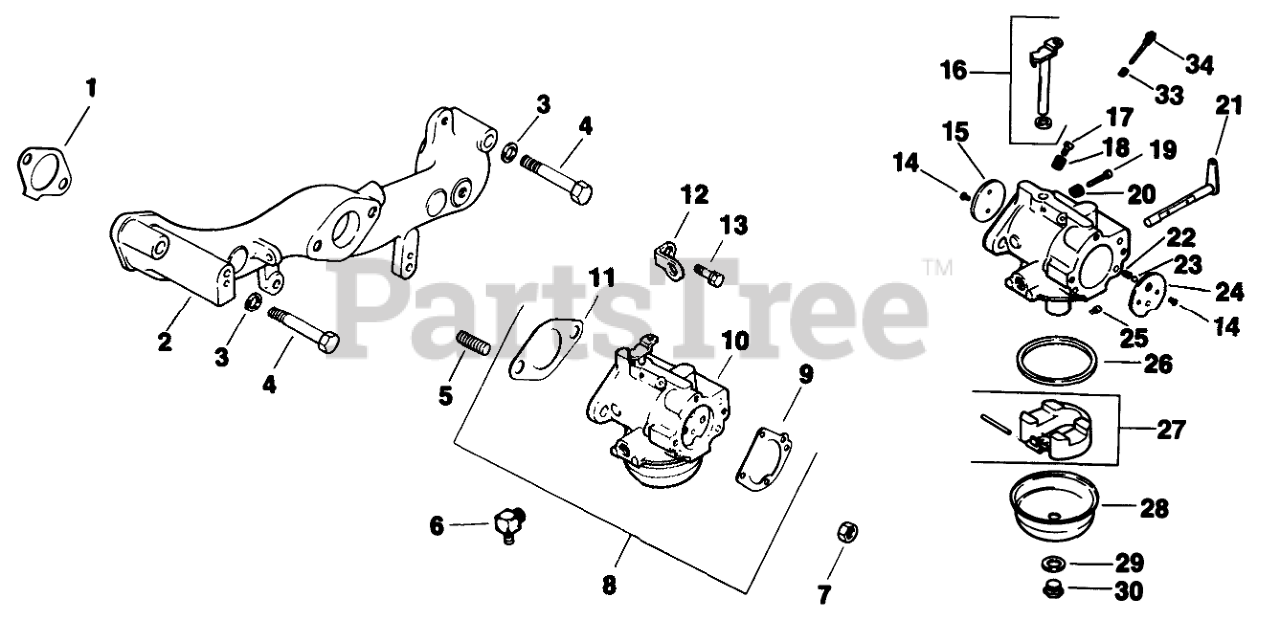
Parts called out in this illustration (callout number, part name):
1	Gasket-Intake
2	Manifold-Intake
3	Washer
4	Screw
5	Stud
6	Connector-90deg.
7	Nut
8	Carburetor Kit W/Linkage (Incl. Ref. #9-10, & 12-27)
9	Gasket-Air Cleaner
10	Carburetor Assembly Ref.
11	Gasket
12	Strap Lifting
13	Screw
14	Screw-Throttle Plate
15	Plate-Throttle
16	Shaft Assembly
17	Valve-Needle
18	Spring
19	Screw
20	Spring
21	Lever-Choke
22	Spring-Choke
23	Ball-Choke
24	Plate-Choke
25	Jet-Main
26	Bowl-Gasket
27	Kit-Float
28	Bowl
29	Gasket-Bowl
30	Screw-Bowl
31	Kit-Carburetor w/Gasket
33	Spring
34	Needle-Main Fuel
